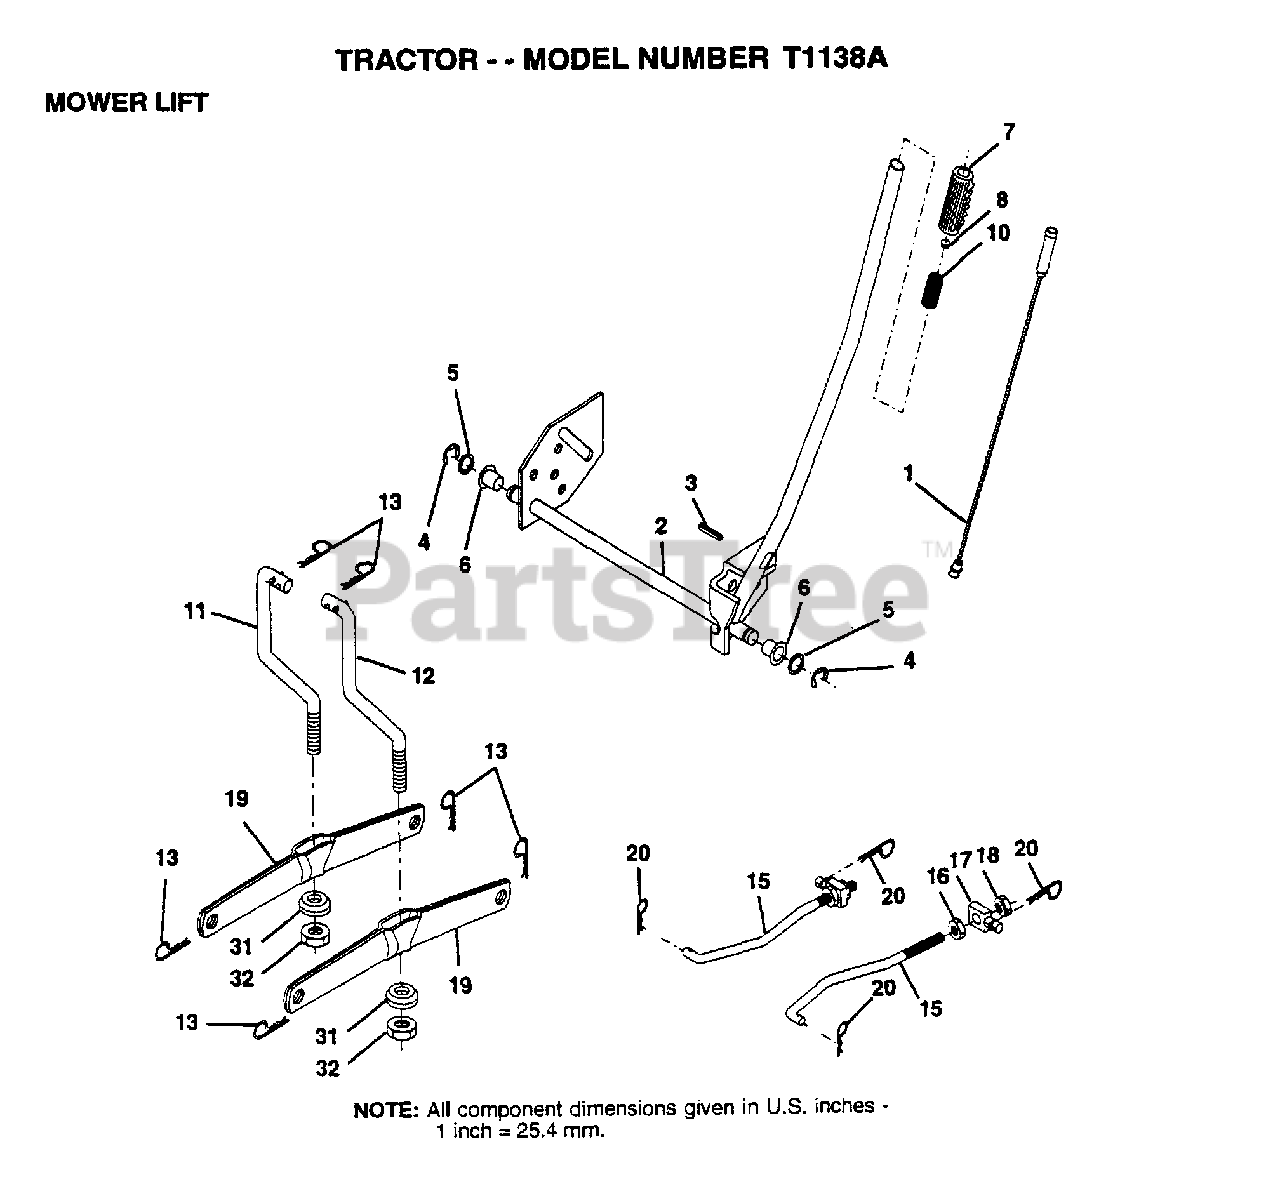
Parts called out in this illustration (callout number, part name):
1	WIRE ASM
3	PIN-GROOVE LT
5	WASHER
6	NYLON BEARING
7	GRIP
15	LINK.FRONT
16	NUT
17	TRUNION
18	NUT.LK.W/WSH.1/2.
19	ARM SUSP REAR
20	RETAINER.SPRING
31	BEARING PVT LH
32	NUT.CROWNLOCK.3/8
